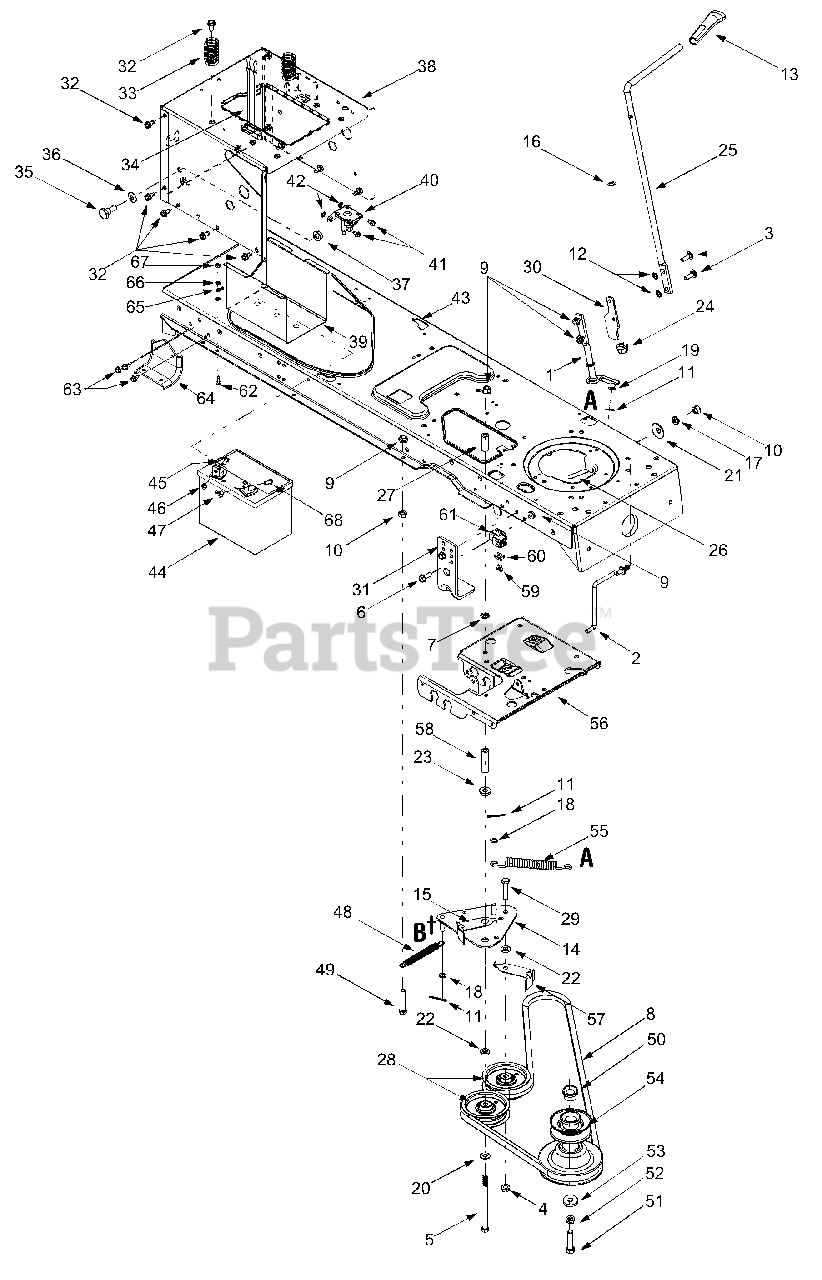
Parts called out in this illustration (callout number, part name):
1	PTO Engagement Lever Assembly
2	Belt Keeper Rod
3	Carriage Screw, 5/16-18 x 1.00
4	Flange Lock Nut, 3/8-16
5	Hex Cap Screw, 3/8-16 x 5.5
6	Hex Head Washer Screw, 5/16-18 x.875
7	Push Nut, 3/8
8	PTO Belt
9	Flange Lock Nut, 5/16-18
10	Hex Nut, 5/16-18
11	Cotter Pin, 1/8 x 1.25
12	Speed Nut,.3125
13	PTO Knob
14	PTO Engagement Plate Assembly
15	Belt Guard
16	Flat Washer,.510 x.750 x.033
17	Lock Washer, 5/16
18	Flat Washer,.385 x.62 x.063
19	Flat Washer, 5/16
20	Flat Washer,.406 x.875 x.059
21	Bell Washer,.39 x 1.13 x.062
22	Flat Washer,.407 x.812 x.135
23	Shoulder Spacer,.380
24	Hex Split Flange Bearing,.5
26	Belt Keeper Rod
27	Spacer, 3/8 x 1.54
28	Idler Pulley, 3.5
29	Hex Cap Screw, 3/8-16 x 1.75
32	Self Tapping Screw, 5/16-18 x.625
33	Compression Spring, 1.28 x 3.125
34	Battery Strap
35	Shoulder Screw,.625 x.5, 7/16-20
36	Bell Washer,.45 x 1.0 x.062
37	Flange Lock Nut, 7/16-20
41	Self Tapping Screw, 1/4-20 x.5
42	Lock Washer, 1/4
45	Hex Cap Screw, 1/4-20 x.75
46	Hex Sems Nut, 1/4-20
47	Wing Nut, 1/4-20
48	Extension Spring,.50 x 5.0
49	Hex Cap Screw, 5/16-18 x 1.75
50	Spacer Cup
51	Hex Head Cap Screw, 7/16-20 x 1.25
52	Lock Washer, 7/16
53	Flat Washer,.450 x 1.25
54	Engine Pulley, 3.56 OD x 5.56
55	Extension Spring,.75 x 6.75
57	Belt Guard
58	Spacer,.375 x 2.5
59	AB Screw, #10-16 x 0.5
60	Switch Plate
61	Switch
62	Self-tapping Screw, 1/4-20 x 0.75
63	Self-tapping Screw, 5/16-18 x.625
65	Lock Washer
66	Lock Washer
67	Hex Nut, 1/4-20
68	Shoulder Screw
